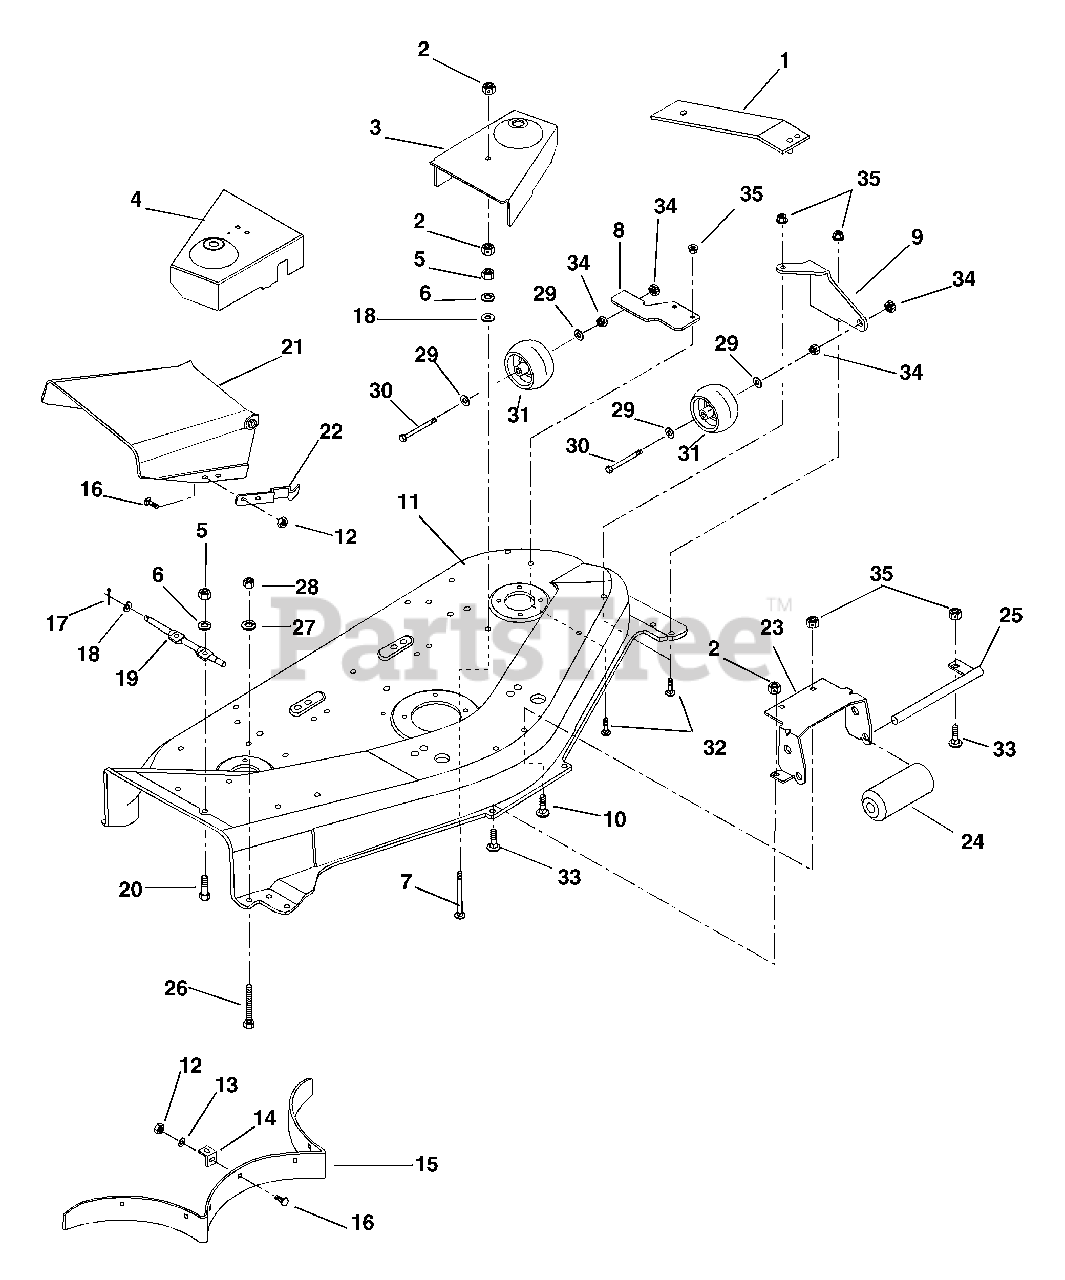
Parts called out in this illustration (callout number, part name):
2	@NUT-LK-CTR .31-18 YWZC
3	COVER, RIGHT HAND
4	COVER, LEFT HAND
5	@NUT-HEX .31-18 YWZC
6	@WSHR-LK .31X.078 REG YWZC
7	BLT-RDHDSQNK .312-18X3.25 YWZC
8	BRACKET, LEFT REAR
9	BRACKET, LEFT FRONT
10	@BLT-RDHDSQNK .31-18X.75 G5YZ
11	MOWER PAN W/ DECALS (G)-RED
12	@NUT-LK-CTR .25-20 YWZC
13	@WSHR-FL-STL.281X.62X.065 YWZC
14	BAFFLE TAB
15	BAFFLE
16	ADAPTER SLEEVE JOHN DEERE
17	@PIN-CTR .09X.75 EXTPRSQCT YWZ
18	@WSHR-FL-STL.406X.812X.065 YWZ
19	HINGE PIN
20	@BLT-HEX .31-18X.75 GR5 YWZC
21	CHUTE EXTENSION
22	FLAT SPRING - ORANGE
23	BRACKET, ROLLER
25	ROLLER SHAFT
26	@BLT-RDHDSQNK .38-16X2.50 G5YZ
27	WSHR-LK .375X.130 YWZC
28	@NUT-HEX .38-16 YWZC
29	WSHR-FL-STL .505X.880X.072 YWZ
30	@BLT-HEX .50-13X4.00 GR5 YWZC
31	WHEEL 5 X 3
32	@BLT-RDHDSQNK .31-18X.75 G5YZ
33	@BLT-RDHDSQNK .31-18X1.00 G5YZ
34	@NUT-LK-CTR .50-13 YWZC
35	@NUT-LK-TOP-FLG .31-18 YWZC
